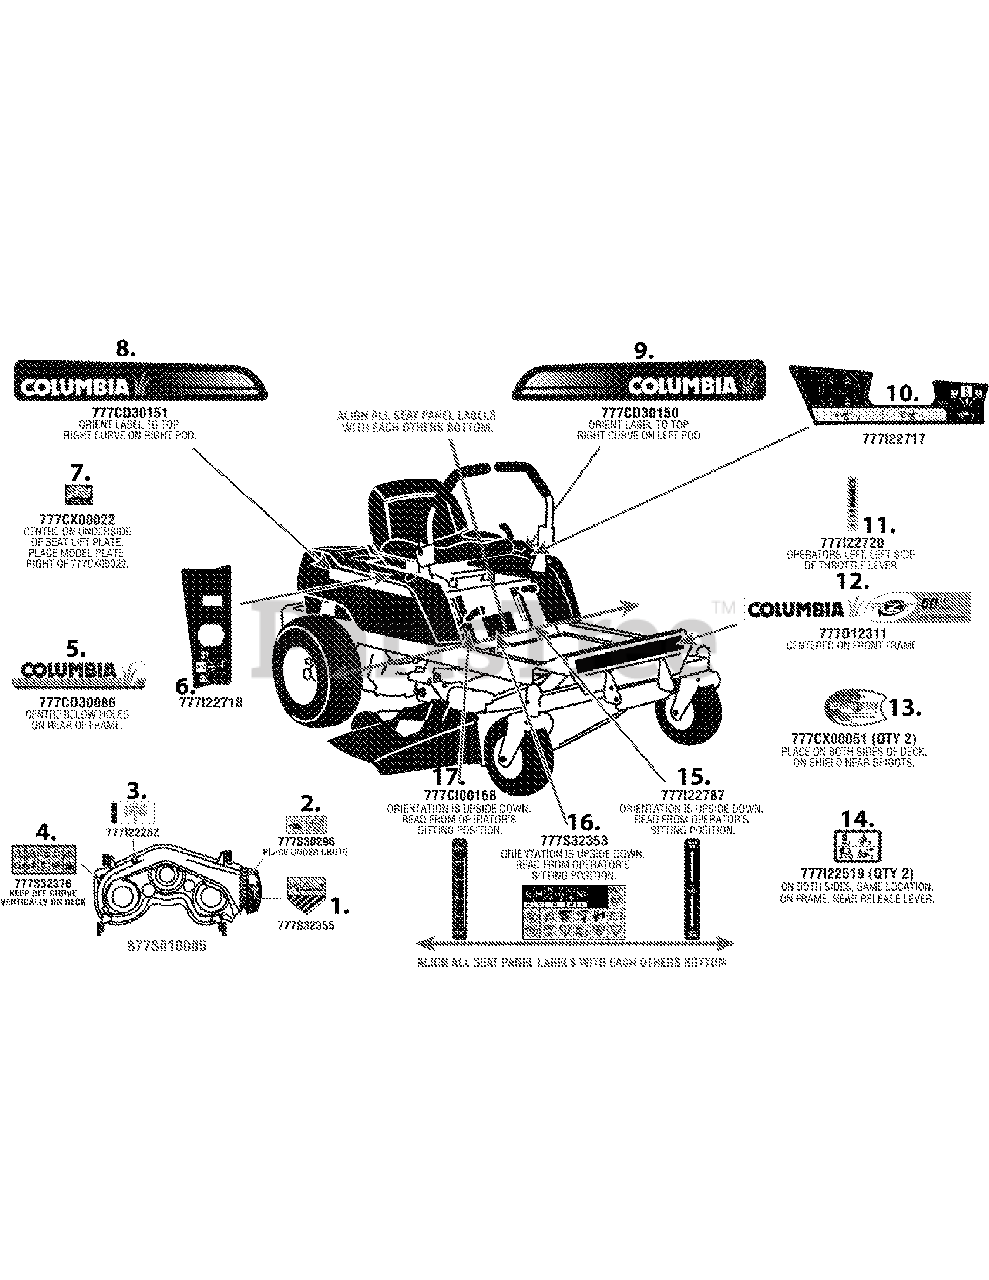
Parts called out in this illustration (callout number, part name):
1	LABEL:RIDER:SAFETY CHUTE DEFL
2	LABEL:RIDER DECK: UNDERCHUTE EXP
3	LABEL-BELT ROUTE
4	LABEL:RIDER:SAFETY DECK
5	LABEL-REAR FENDER COLUMBIA
6	LABEL-RH CONTROL
7	LABEL- MADE IN USA
8	LABEL-RH POD
9	LABEL-LH POD
10	LABEL-LH CONTROL W/CHOKE
11	LABEL-THROTTLE
12	LABEL-FRNT FRAME 50" COLUMBIA
13	LABEL-DECK WASH
14	LABEL-TRNMSN RELEASE
15	LABEL-PARK BRAKE
16	LABEL-RDR SAFETY
17	LABEL-HANDLE HEIGHT
